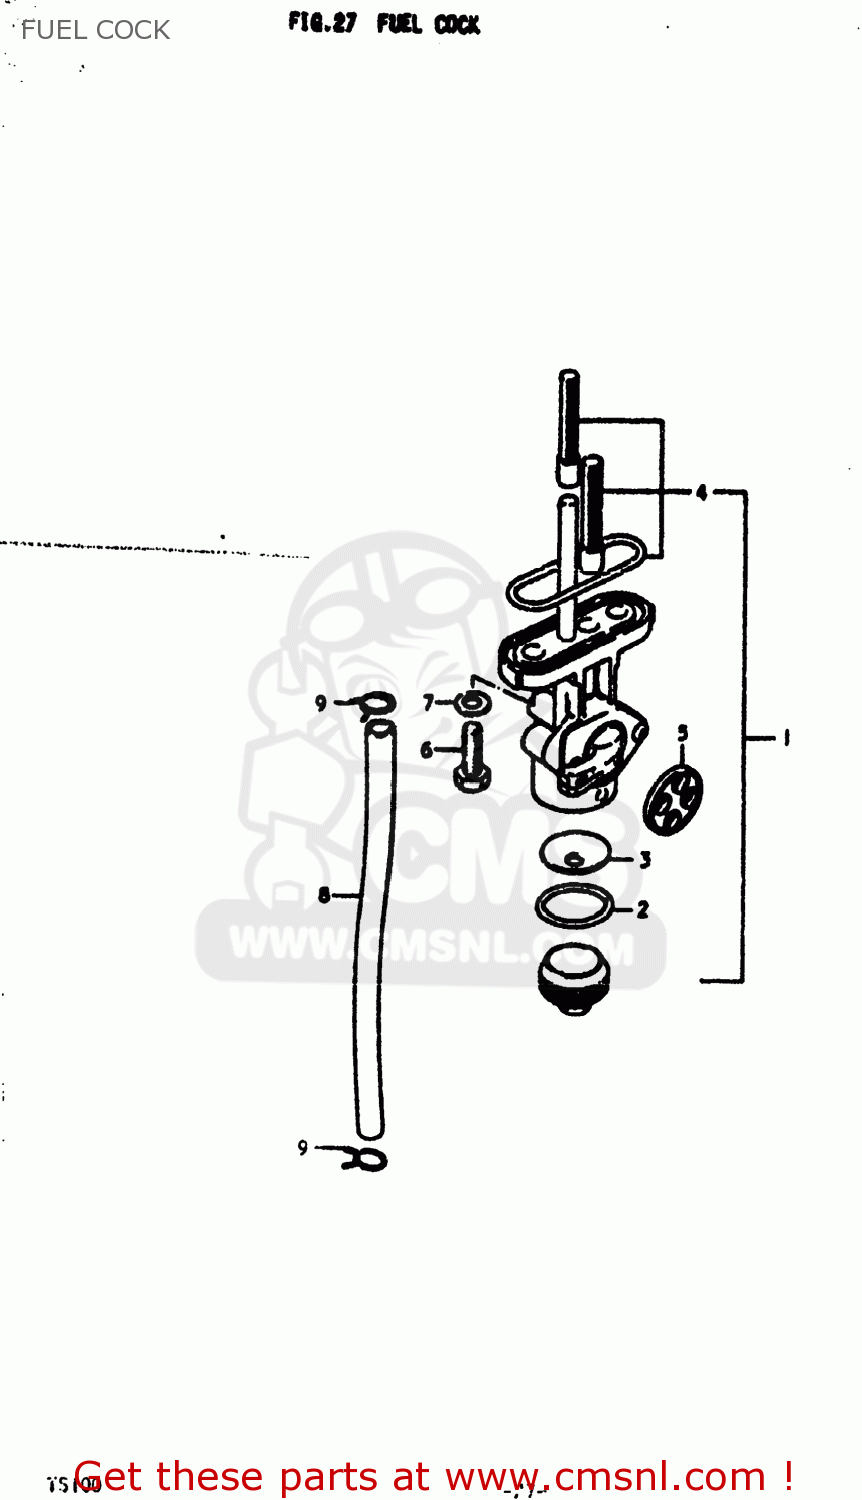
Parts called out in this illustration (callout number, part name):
1	COCK ASSEMBLY,FUEL
2	GASKET,FILTER (NAS)
3	NET,STRAINER
4	FILTER SET,FUEL COCK
5	GASKET,LEVER (NAS)
6	BOLT L:16
7	GASKET
8	HOSE
